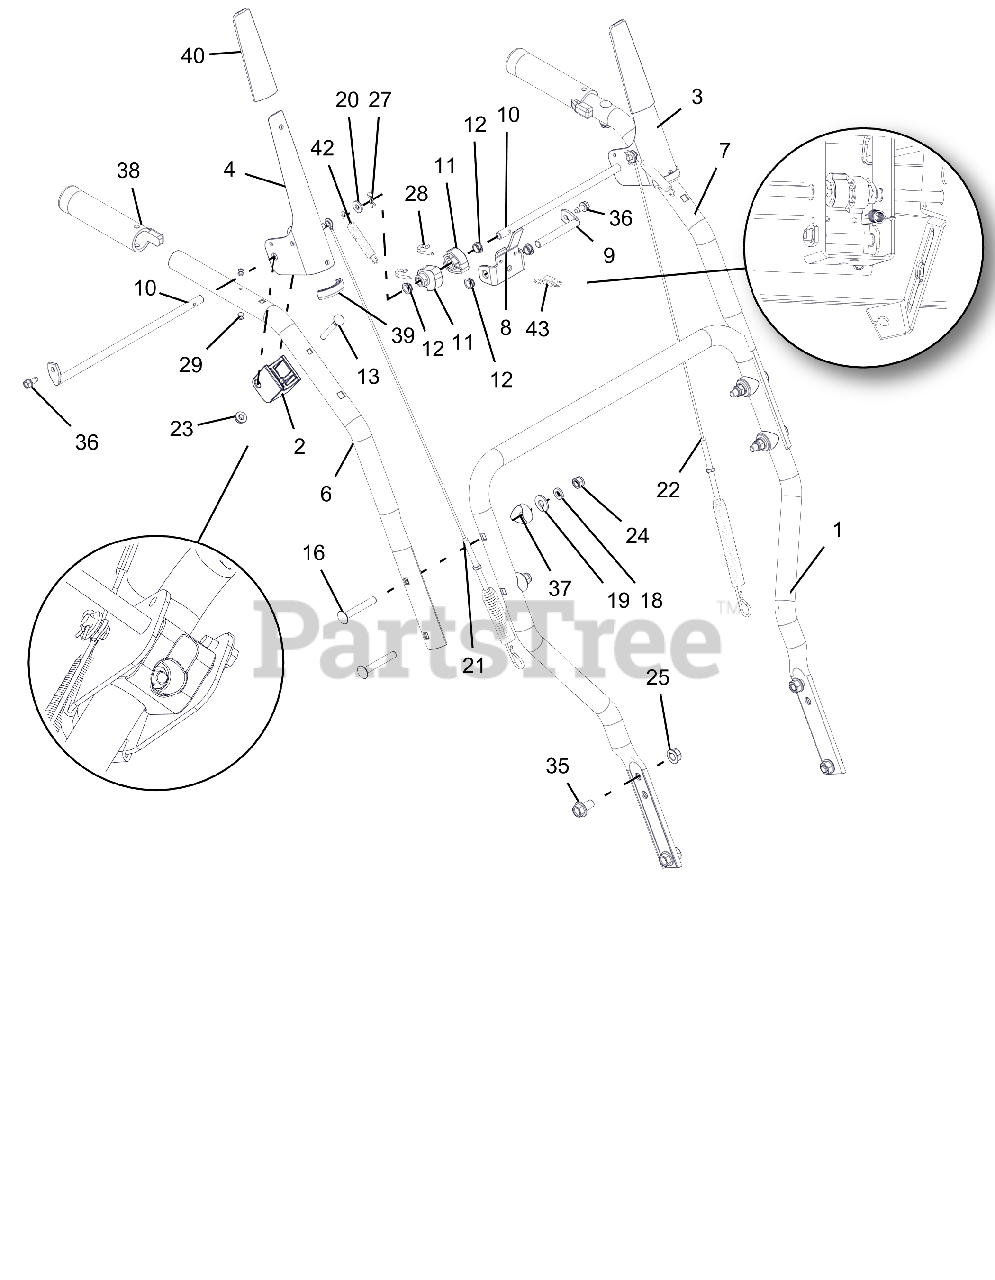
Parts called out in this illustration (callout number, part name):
1	HANDLEBAR, LOWER
2	BLOCK, CLUTCH HANDLE
3	WLDMT, CLUTCH HANDLE - LH
4	WLDMT, CLUTCH HANDLE - RH
6	HANDLEBAR, UPPER - RH
7	HANDLEBAR, UPPER - LH
8	BRKT, INTERLOCK ARM
9	ROD, PIVOT - INTERLOCK
10	ROD, PADDLE MOUNT - PRO
11	CAM, INTERLOCK
12	BSHG, POLYLINER-.38 SNAPIN
13	BLT, RDHDXLSQNK .25-20X2.0 G5YZ
16	BLT-RDHDSQNK .31-18X2.25 G5 Y
18	WSHR-LK .31X.097 HVY YWZC
19	WSHR-FL-STL.38X.875X.083 YWZC
20	WSHR-FL-STL.281X.62X.065 YWZC
21	CABLE, AUGER
22	CABLE, UPPER TRACTION
23	NUT, LK-CTR-FLG .25-20 YWZC
24	NUT-LK-NYL .312-18 YWZC
25	NUT, LK-TOP-FLG .38-16 YWZC
27	PIN-HAIR INT .06X.18X.77
28	PIN, SPRING CLIP
29	RVT-POP #43 .125x.313 STL ZINC
35	BLT-SERHFWH .38-16X.75 YWZC
36	SCR-TAP .25-20X.50 HWH TR YWZ
37	SPCR, HANDLEBAR
38	GRIP, HANDLE - HEATED
39	STRIP, EDGE - CLUTCH HANDLE
40	SLV, CLUTCH HANDLE
42	SPRG, EXTENSION
43	SPRG, EXTENSION
